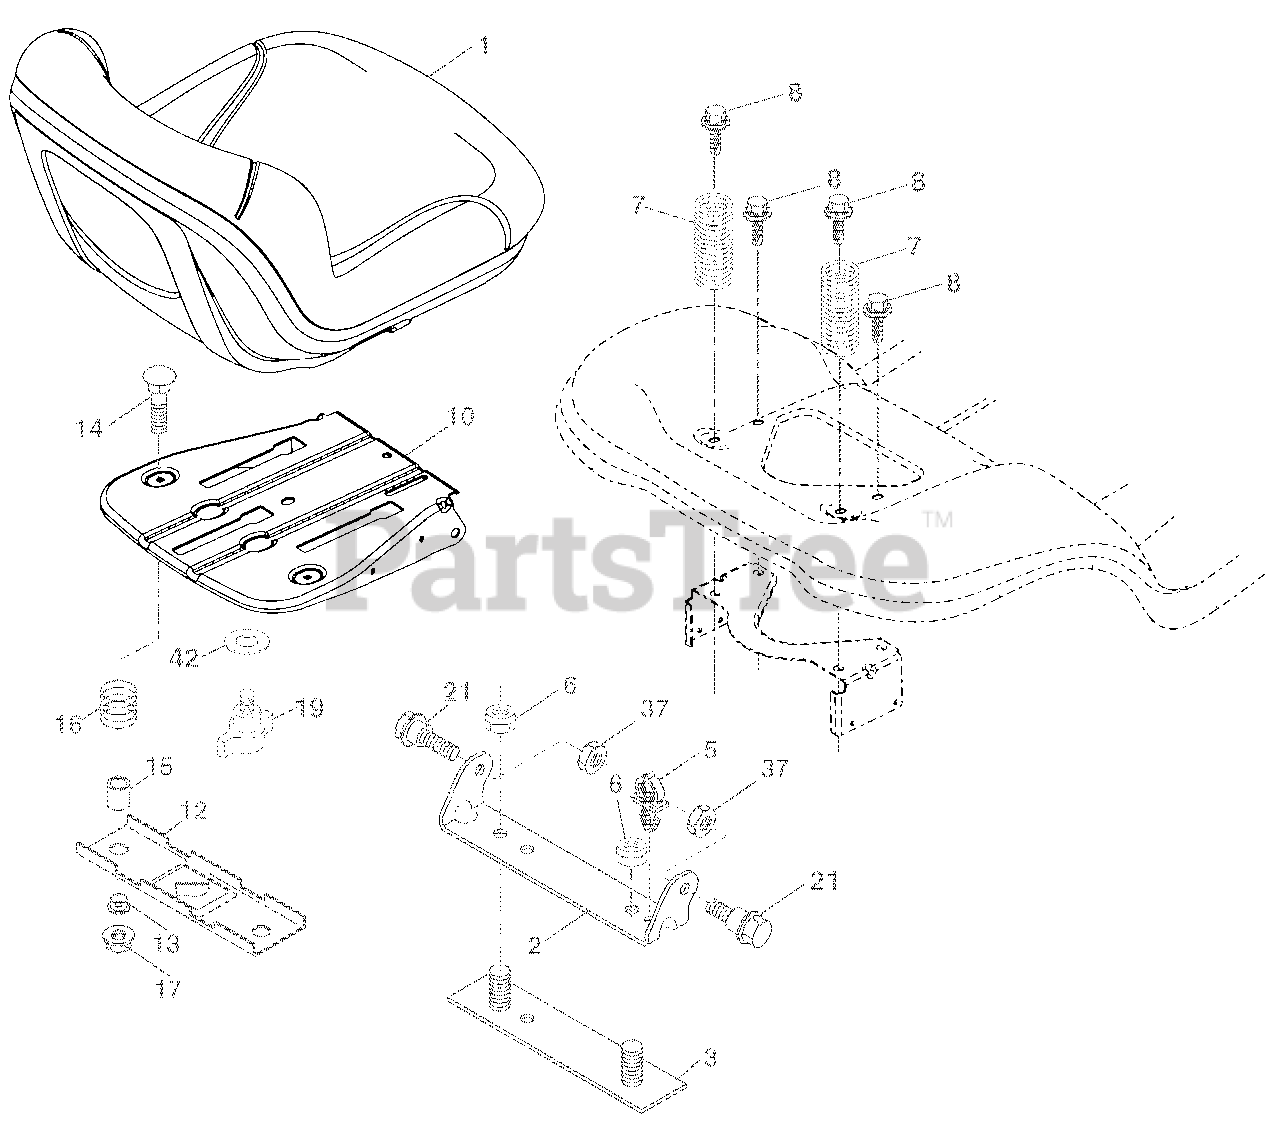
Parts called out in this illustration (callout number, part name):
2	BRACKET.PIVOT.FENDER.2002
3	STRAP ASM.FENDER.94
5	CLIP.PUSH-IN.HINGED
6	Locknut, Washer Insert 3/8-16
7	SPRING.SEAT.CPRSN.2.250.BLK.ZI
8	BOLT.5/16-18UNCX3/4 W/SEMS.BLK
10	PAN, SEAT
12	BRACKET.MNT.OPC.SW.SEAT.TEX LT
13	BUSHING.SNAP.BLK.NYL..50 ID.
14	BOLT.RDHD.SHT.NK.1/4-20X1-1/2
15	SPACER.SPLIT..28X.96.YEL.ZINC
16	SPRING.CPRSN.PLATE.SW.1.310.GA
17	NUT.LOCK.1/4 LGE.FLG.GR.5.ZINC
19	KNOB.SEAT ADJ.3/8-16"TEX
21	BOLT.SHLD.5/16-18 UNC-2A.BLK D
37	Locknut, Washer Insert 5/16-18
42	WASHER.CUP.SEAT.TEX LT
